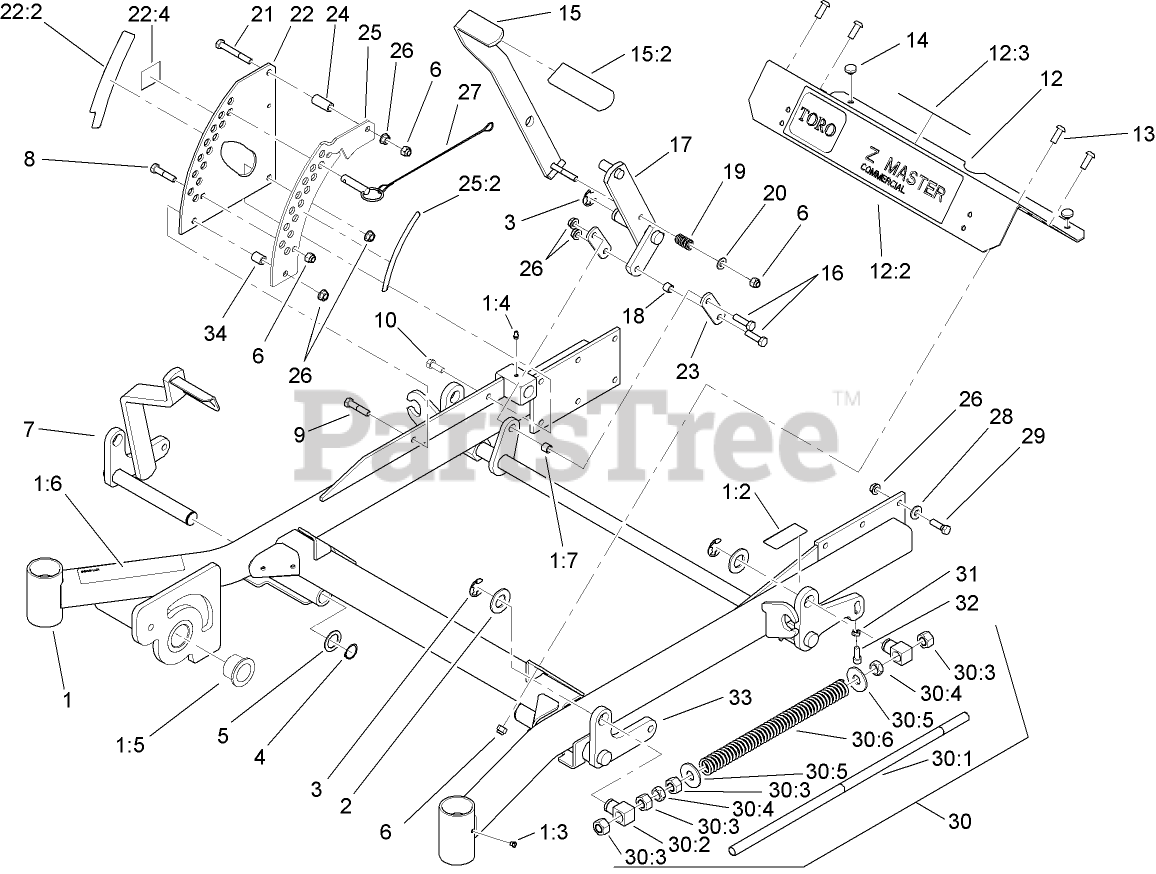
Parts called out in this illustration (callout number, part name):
1	FRAME ASM
1:2	DECAL-BRAKE, PARKING
1:4	FITTING-GREASE
1:5	BUSHING
1:6	DECAL-WARNING
1:7	Bushing
2	WASHER-FLAT
3	RING-RETAINING, EXT
4	RING-RETAINING
5	WASHER-SPACER
6	NUT-LOCK, NI
7	LIFT-DECK, RH FRONT
8	SCREW-HH
9	SCREW-HH
10	SCREW-HH
12	FOOTREST
12:3	DECAL-DANGER, SLOPE
13	SCREW-HSBH
14	BUMPER
15	LIFT LEVER/GRIP ASM
15:2	GRIP-LEVER, LIFT
16	SCREW-HH
17	ARM-LIFT, DECK
18	Bushing
19	SPRING-COMPRESSION
20	WASHER-FLAT
21	SCREW-HH
22	PLATE-DECK LIFT, OUTER (CE)
22:2	DECAL-HEIGHT, DECK
22:4	DECAL-NOISE
23	ARM-LIFT, DECK
24	BUSHING-LEVER, LIFT
25	PLATE-DECK LIFT, INNER (CE)
25:2	DECAL-HEIGHT, DECK
26	NUT-HHF, WHIZ
27	Hitch Pin ASM
28	WASHER-BELLEVILLE
29	SCREW-HH
30	Front Frame Spring ASM
30:1	ROD-LIFT, DECK
30:2	SWIVEL-DECK MOUNT, REAR
30:3	NUT-HEX
30:4	NUT-JAM
30:5	WASHER-FLAT
30:6	SPRING-SUPPORT, DECK
31	NUT-JAM
32	SCREW-HSH
33	LIFT-DECK, LH
34	BUSHING-LEVER, LIFT
